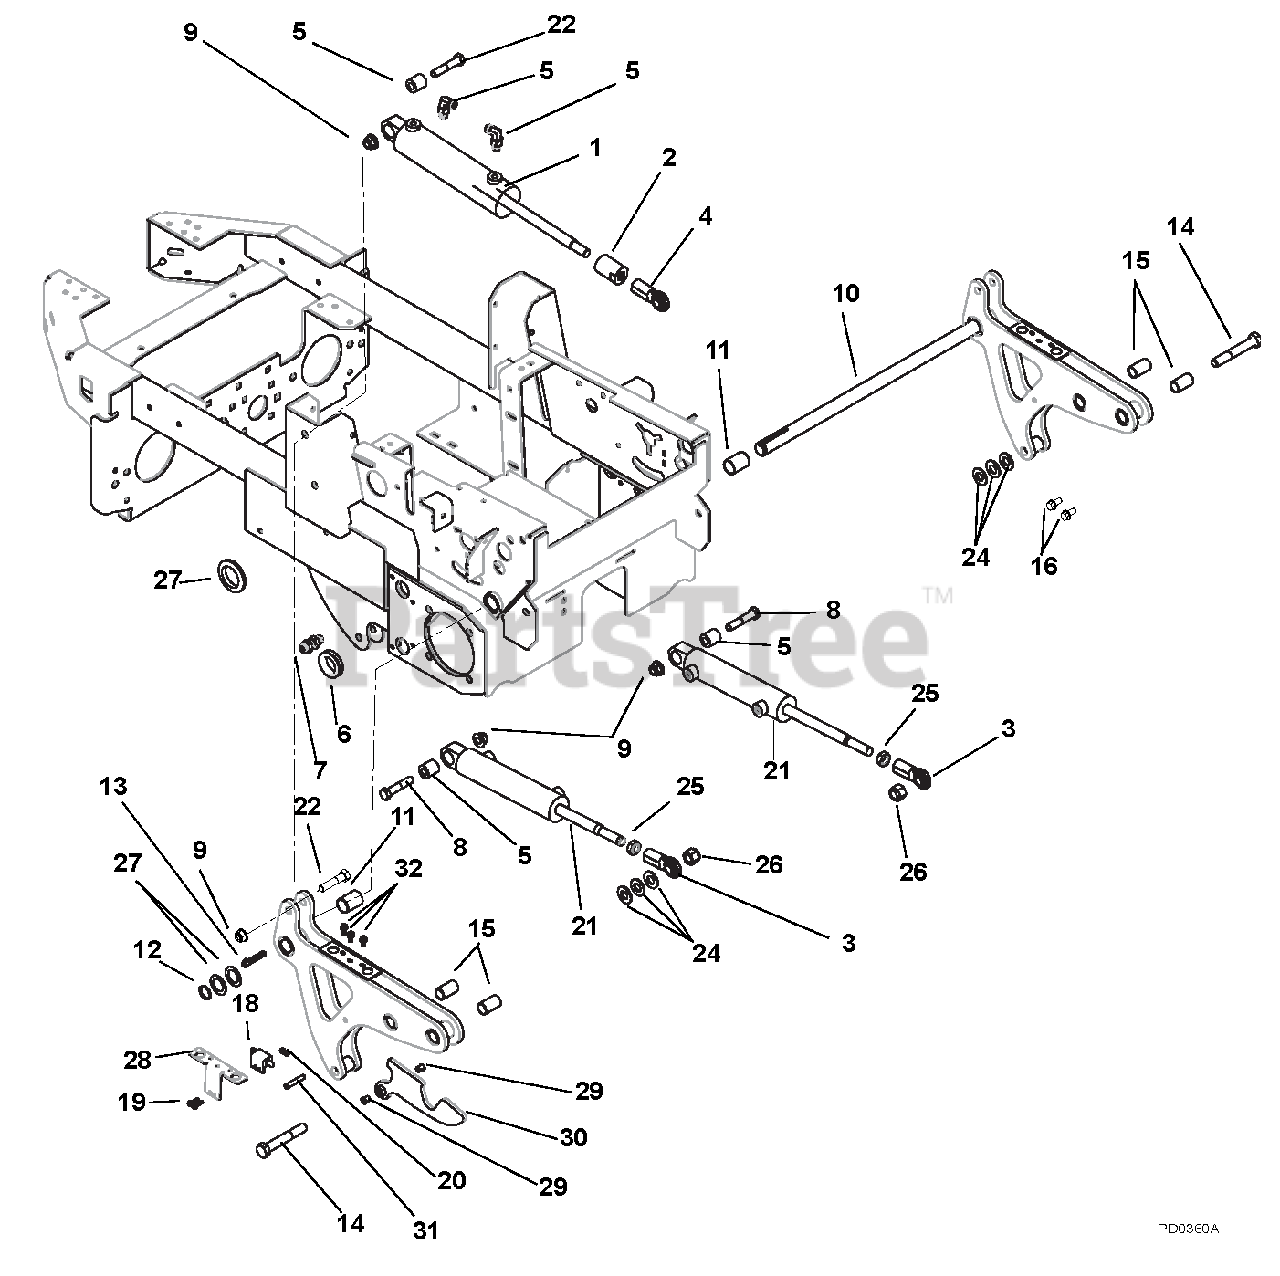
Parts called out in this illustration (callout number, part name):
1	CYLINDER, HYD. DECK LIFT
2	SPACER,CYLINDER STOP,1.50X2.00
3	ROD END, 5/8 RH - FEMALE
4	ADPTR,HYD FTG 90 M4F-M6O C5OLO
5	BUSHING, .516X1.000X1.050 LG
6	GROMMET 1.25ID X 1.5OD
7	FTG,HYD BULKHEAD M4F-M4F
8	@BLT-HEX .50-13X2.25 GR5 YWZC
9	@NUT-LK-NYL-FLG .50-13 YWZC
10	WMT,MAIN ARM ASSY W/SHAFT
11	BSHG,1.00ID X 1.125OD X 1.50LG
12	RG-RTNG-EXT 1.00X.078
13	KEY, GIB .25 X 1.5
14	BLT-HEX .62-11X4.0 GR5 YWZC
15	BRG,.75X.875X1.50
16	@SCR-TAP .38-16X.75 HWH TR YWZ
18	SWITCH- SINGLE POLE N.O.
19	SCR-MCH 10-24X.75 HWH YWZC
20	NUT-LK-NYL 10-24 W/INSRT YWZC
21	CYLINDER, LIFT
22	@BLT-HEX .50-13X2.50 GR5 YWZC
23	GROMMET 1.70ID X 2.0OD
24	@WSHR-FL-STL.656X1.31X.095 YWZ
25	NUT-JAM .625-18 YWZC
26	@NUT-LK-NYL .625-11 YWZC
27	WSHR-HDND-THRUST 1.00X1.55X.03
28	BRKT,SWITCH MOUNTING - RED
29	BSHG-FLG, SPLIT NYLINER .31"ID
30	WMT,ROCKER ARM,SWITCH - RED
31	ROLL PIN 5/16 X 1 7/8
32	SCR-TAP .25-20X.50 HWH TR YWZ
